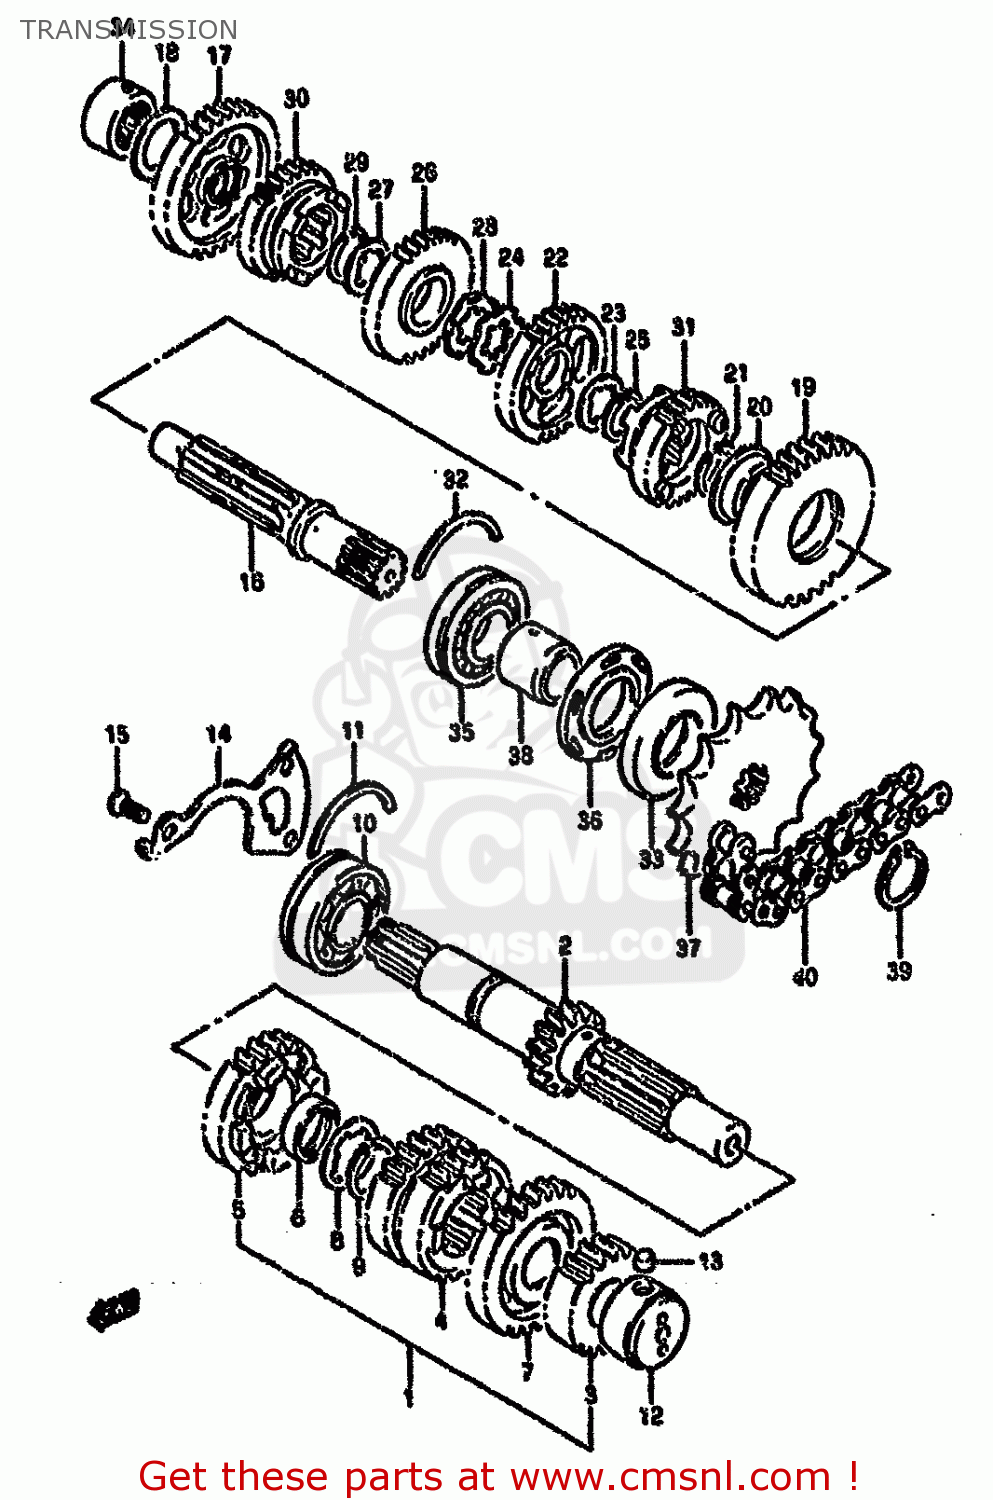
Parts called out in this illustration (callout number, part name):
1	SHAFT COMP,COUNTER
2	SHAFT,COUNTER (NT:13)
3	GEAR,2ND DRIVE(NT:18)
4	GEAR,THIRD DRIVE (NT:21/2
5	GEAR,FIFTH DRIVE (NT:26)
6	BUSHING 25X29X10
7	GEAR,SIXTH DRIVE (NT:27)
8	WASHER
9	CIRCLIP
10	BEARING(25X62X17)
11	C-RING
12	ROLLER BEARING (20X34X2
13	PIN
14	PLATE,COUNTERSHAFT BEARING
15	SCREW ,6X16
16	SHAFT,DRIVE
17	GEAR,FIRST DRIVEN
18	WASHER
19	GEAR,SECOND DRIVEN
20	BUSHING
21	CIRCLIP
22	GEAR,THIRD DRIVEN
23	WASHER,LOCK
24	WASHER,LOCK
25	CIRCLIP
26	GEAR,FOURTH DRIVEN
27	WASHER,LOCK
28	WASHER
29	CIRCLIP
30	GEAR,5TH DRIVEN(NT:25)
31	GEAR,SIXTH DRIVEN
32	C-RING
33	SEAL,OIL(32X62X7)
34	ROLLER BEARING (20X34X1
35	BEARING(25X62X17)
36	SEAL,OIL(32X62X5.5)
37	SPROCKET,ENGINE
38	SPACER,ENGINE SPROCKET
39	CIRCLIP
40	CHAIN(DID520VM,110L)
